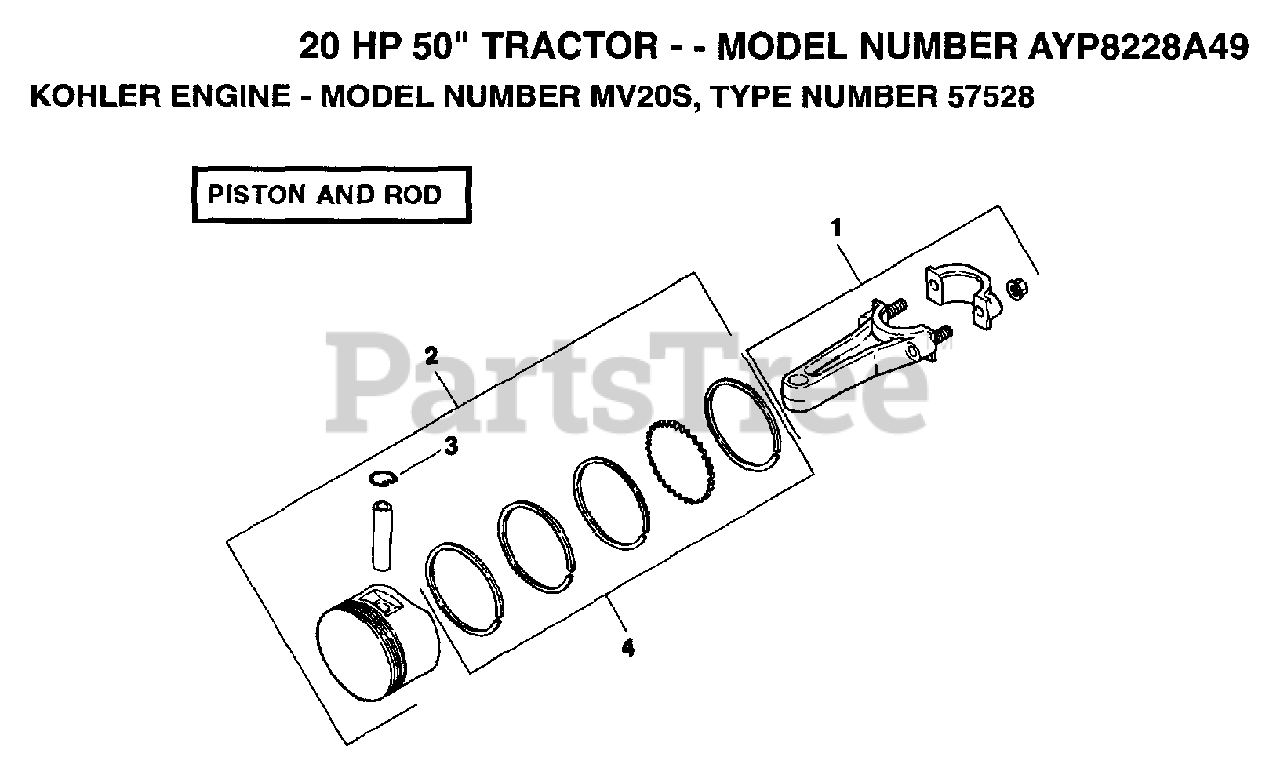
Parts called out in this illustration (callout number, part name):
1	CONNECTING ROD
1	CONNECT. ROD .010"
2	PISTON W/RING SET
2	PISTON W/RING SET .003"
2	PISTON W/RING SET .010"
2	PISTON W/RING SET .020"
2	PISTON W/RING SET .030"
3	RETAINER, PISTON PIN
4	RING SET, .003"
4	RING SET, .010"
4	RING SET, 020"
4	RING SET, .030"
